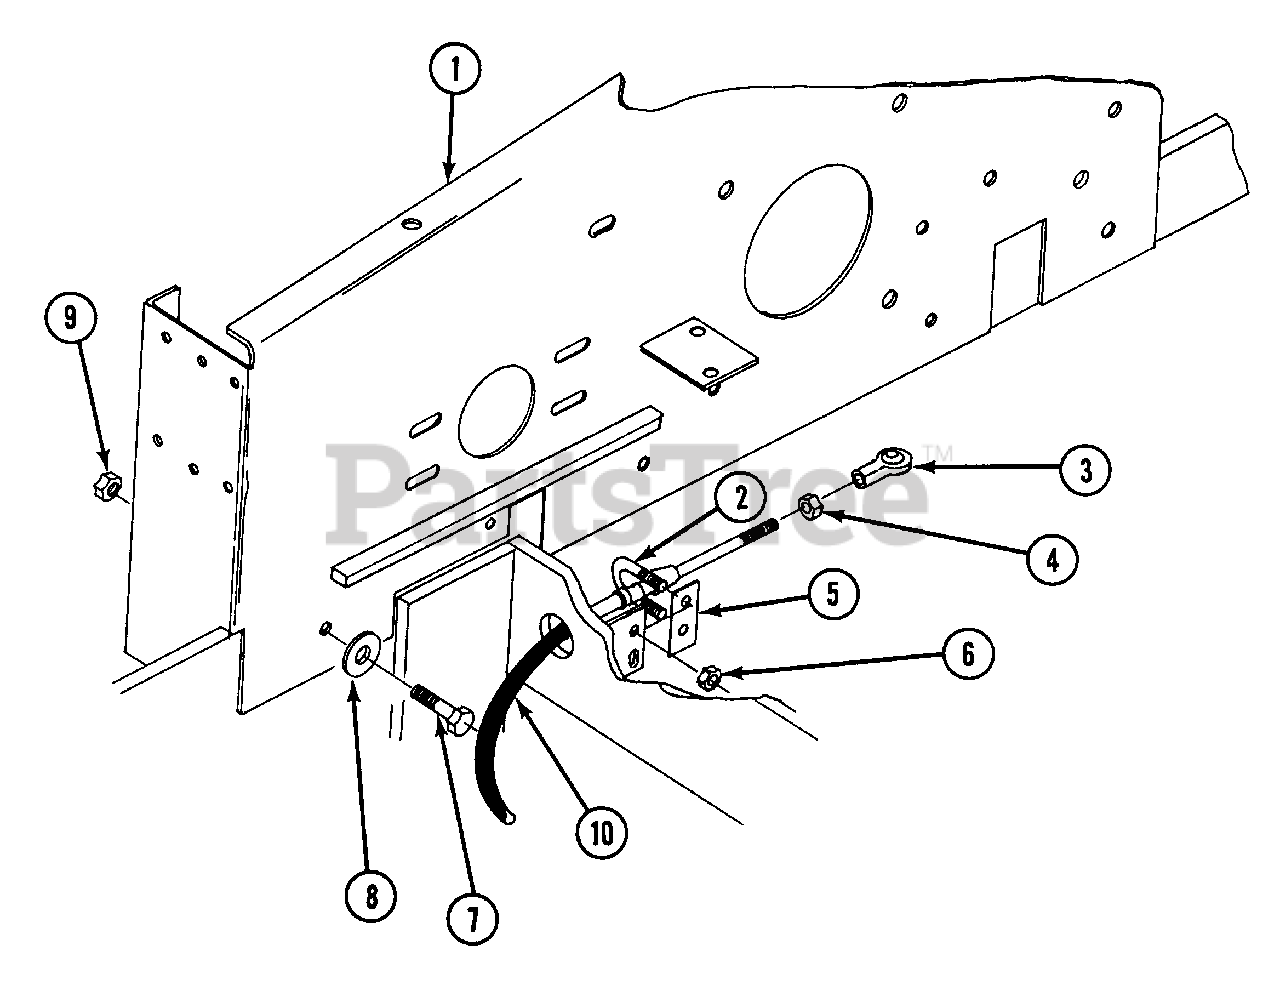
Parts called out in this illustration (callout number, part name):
1	SIDE PLATE WLDT. LEFT
1	SIDE PLATE WLDT. RIGHT
2	U-BOLT, 5/16-18 X 1-3/16
3	BALL JOINTS FEMALE 1/4-28
4	NUTS HEX 1/4-28 (COMES WITH #10)
5	U-BOLT SPACER
6	LOCKNUT, HEX, 5/16-18 THIN HEIGHT W/NYLOC
7	CAPSCREW, HEX, 3/8-24 X 1-1/4 GR.5
8	WASHER, .406 ID X 1.240 OD. .168 THK.
9	LOCKNUT, 3/8-24 W/NYLOC
10	PUSH-PULL CABLE, SERIES 40 LEFT, 64" OAL
10	PUSH-PULL CABLE, SERIES 40 RIGHT, 55" OAL
